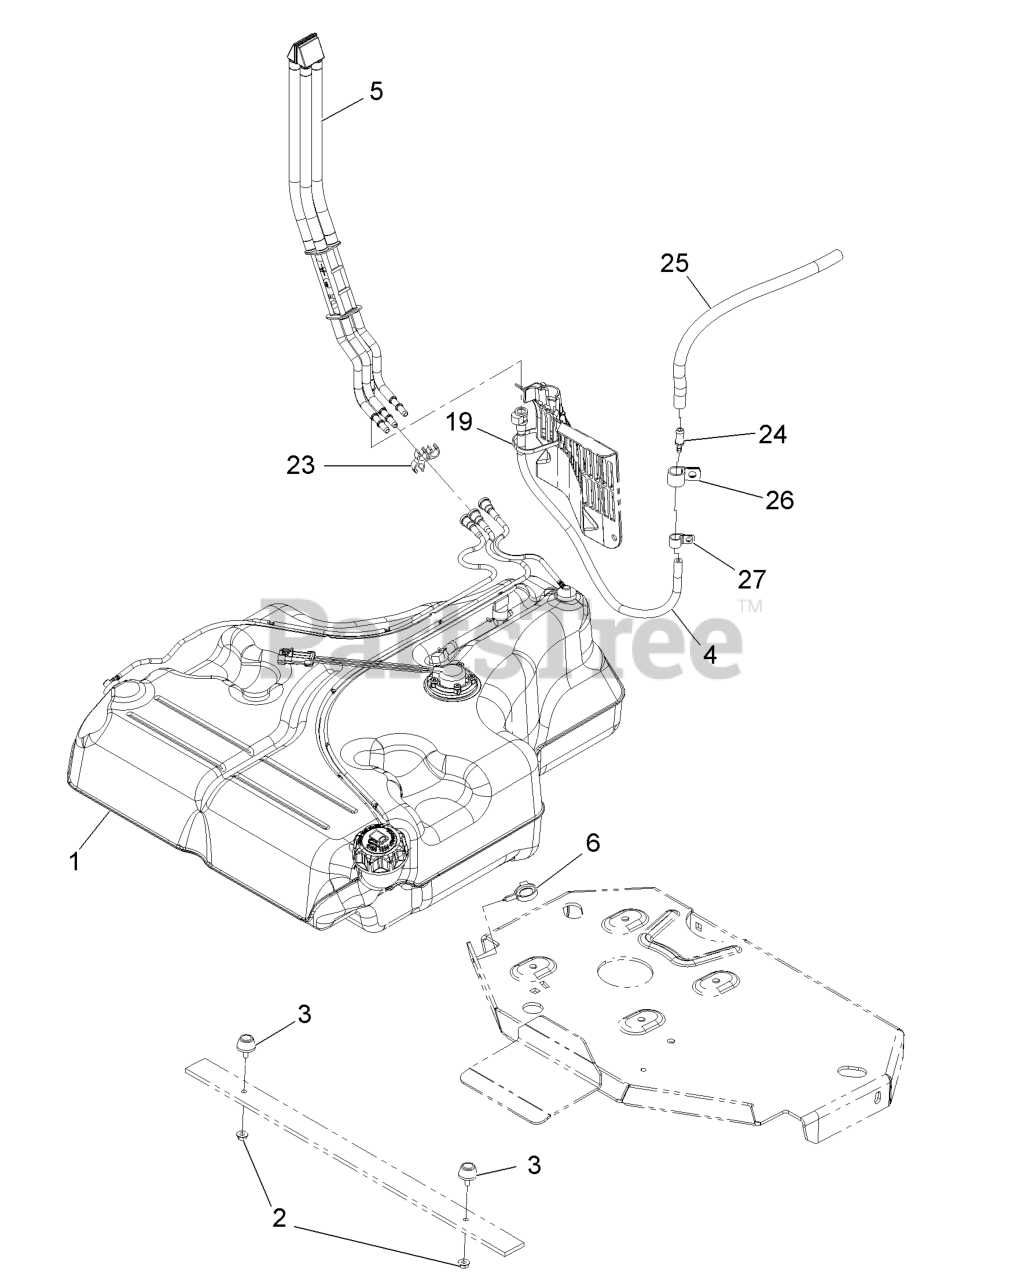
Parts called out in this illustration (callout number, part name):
3	BUMPER-RUBBER
4	HOSE ASM
5	FUEL MANIFOLD VENT ASM
6	CLAMP-HOSE
19	TIE-PLASTIC
23	CLIP-SPACER
24	FITTING-STRAIGHT
25	HOSE-FUEL
26	CLIP-LOOM
27	CLIP-LOOM
